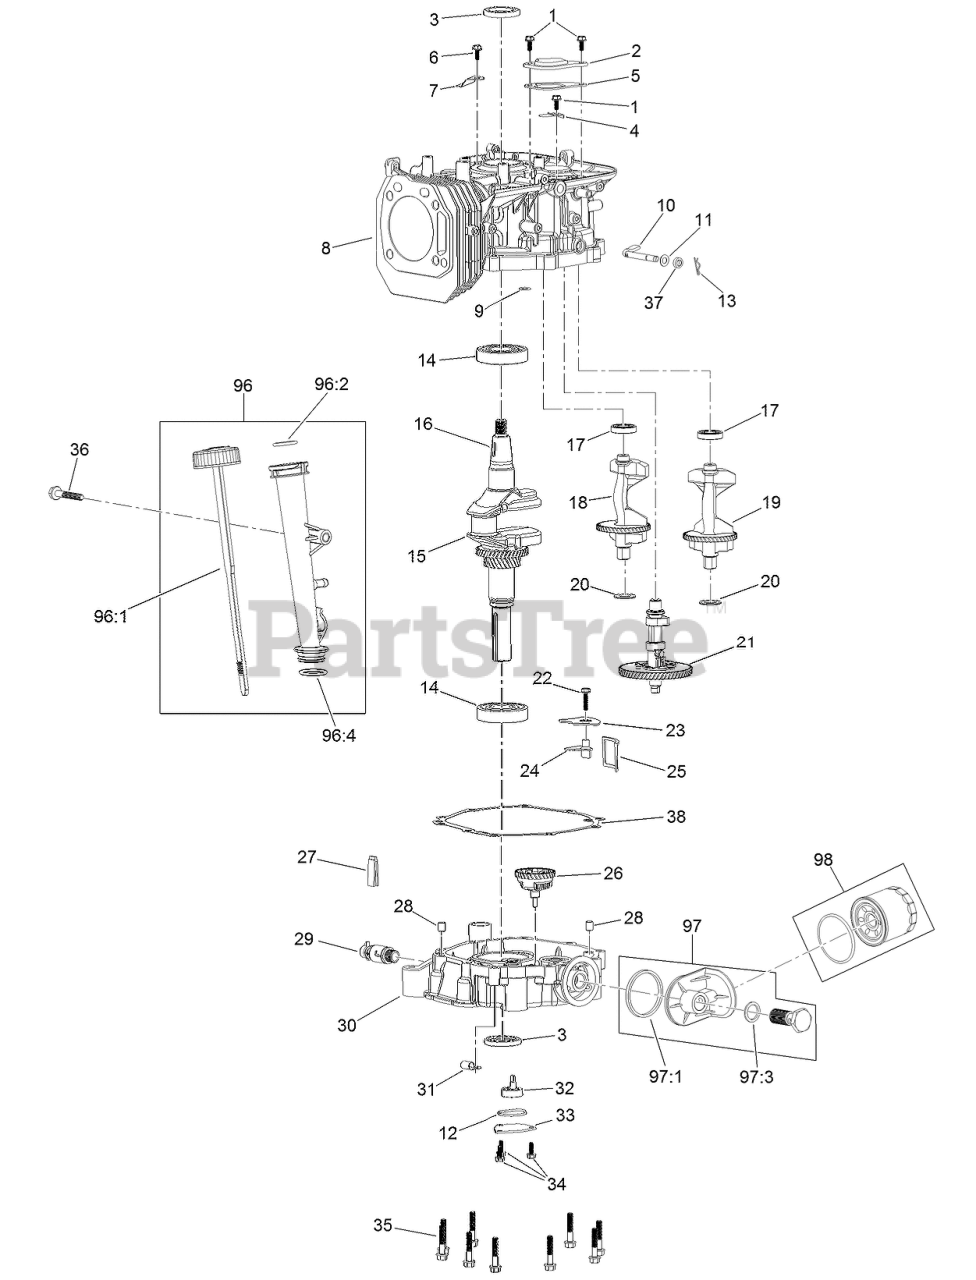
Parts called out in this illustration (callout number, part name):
1	SCREW-HHF
2	PLATE-BREATHER
3	SEAL-OIL
4	VALVE-REED
5	GASKET-BREATHER
6	SCREW-HHF
7	RETAINER
8	CRANKCASE
9	O-RING
10	SHAFT-GOVERNOR
11	WASHER-PLAIN
12	SEAL-PUMP, OIL
13	PIN-HAIR
14	BEARING-BALL
15	CRANKSHAFT
16	KEY-WOODRUFF
17	BEARING-BALL
18	SHAFT-BALANCE, R
19	SHAFT-BALANCE, L
20	WASHER
21	CAMSHAFT
22	SCREW-HHF
23	COVER-STRAINER, OIL
24	PLATE-BAFFLE, OIL
25	STRAINER-OIL
26	GEAR-GOVERNOR
27	DEFLECTOR-OIL, RUBBER
28	PIN-DOWEL
29	VALVE-DRAIN, OIL
30	COVER-CRANKCASE
31	CLAMP-HOSE
32	OIL PUMP ASM
33	COVER-PUMP, OIL
34	SCREW-HHF
35	SCREW-HHF
36	SCREW-HHF
37	SEAL-OIL
38	GASKET-CRANKCASE
96	DIPSTICK AND TUBE KIT
96:1	DIPSTICK ASM
96:2	O-RING
96:4	O-RING
97	OIL ADAPTOR KIT
97:1	SEAL-ADAPTOR, OIL
97:3	WASHER-FILTER, OIL
98	FILTER-OIL
